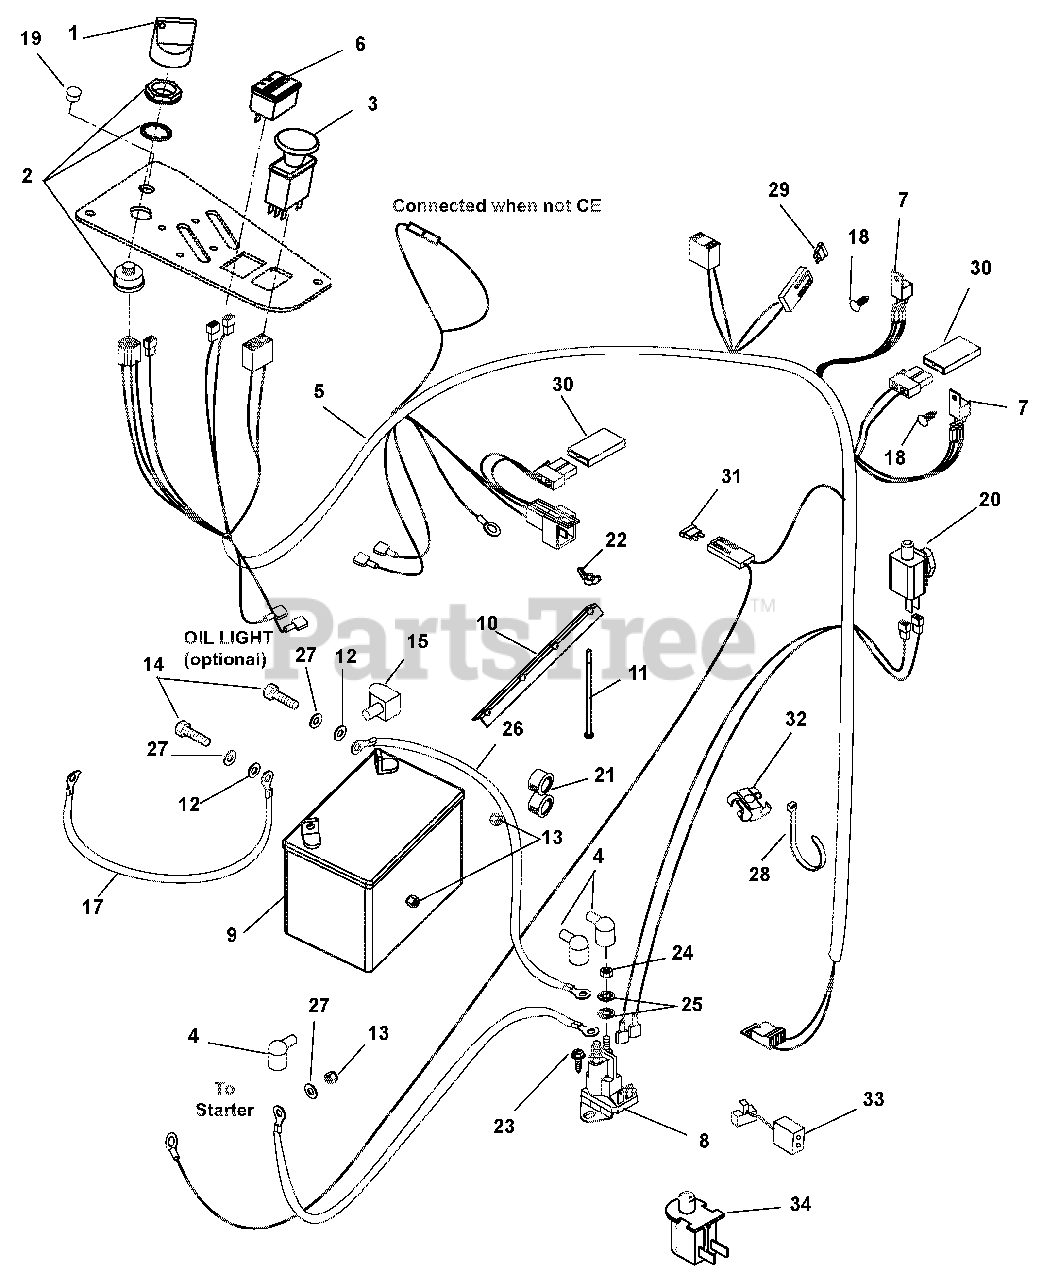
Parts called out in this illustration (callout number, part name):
1	Key with Shield
2	Switch, Ignition
3	Switch, Clutch
4	Boot, Eyelet Terminal
5	Harness, CZ Remote SOL.
6	Hour Meter with Maintenance
7	Relay, Sealed with Diode 8 00696900 1 Solenoid
10	Hold Down
11	Bolt, Round Head Square Neck .25-20 x 7.50
12	Washer, Flat Steel .281 x .620 x .065
13	Nut, Hex .25-20
14	Bolt, Hex .25-20 x .75 Grade 5
15	Insulator
16	Cable, Positive Battery 9.00"
17	Cable, Negative Battery
18	Rivet, .25 Nylon Panel
19	Plug, Hole .50 Diameter
20	Switch, Single Pole (N.O.) – Brake Switch
21	Bushing, Panel Snap .687 x .875 x .56
22	Nut, Locking Wing .25-20
23	Screw, Tapping .25-20 x .50 Hex Washer Head
24	Nut, Jam .31-24
25	Washer, Star Washer .31 x .078 Regular
26	Cable, Starter
27	Washer, Lock .25 x .062
28	Tie, Cable LG 5.50
29	Fuse 20 Amp
30	Diode, Connector Shell
31	Fuse, 25 Amp
32	Clip,T .31-.38
33	Harness, Adapter Clutch
34	Switch, Snap Mounting N.O.
